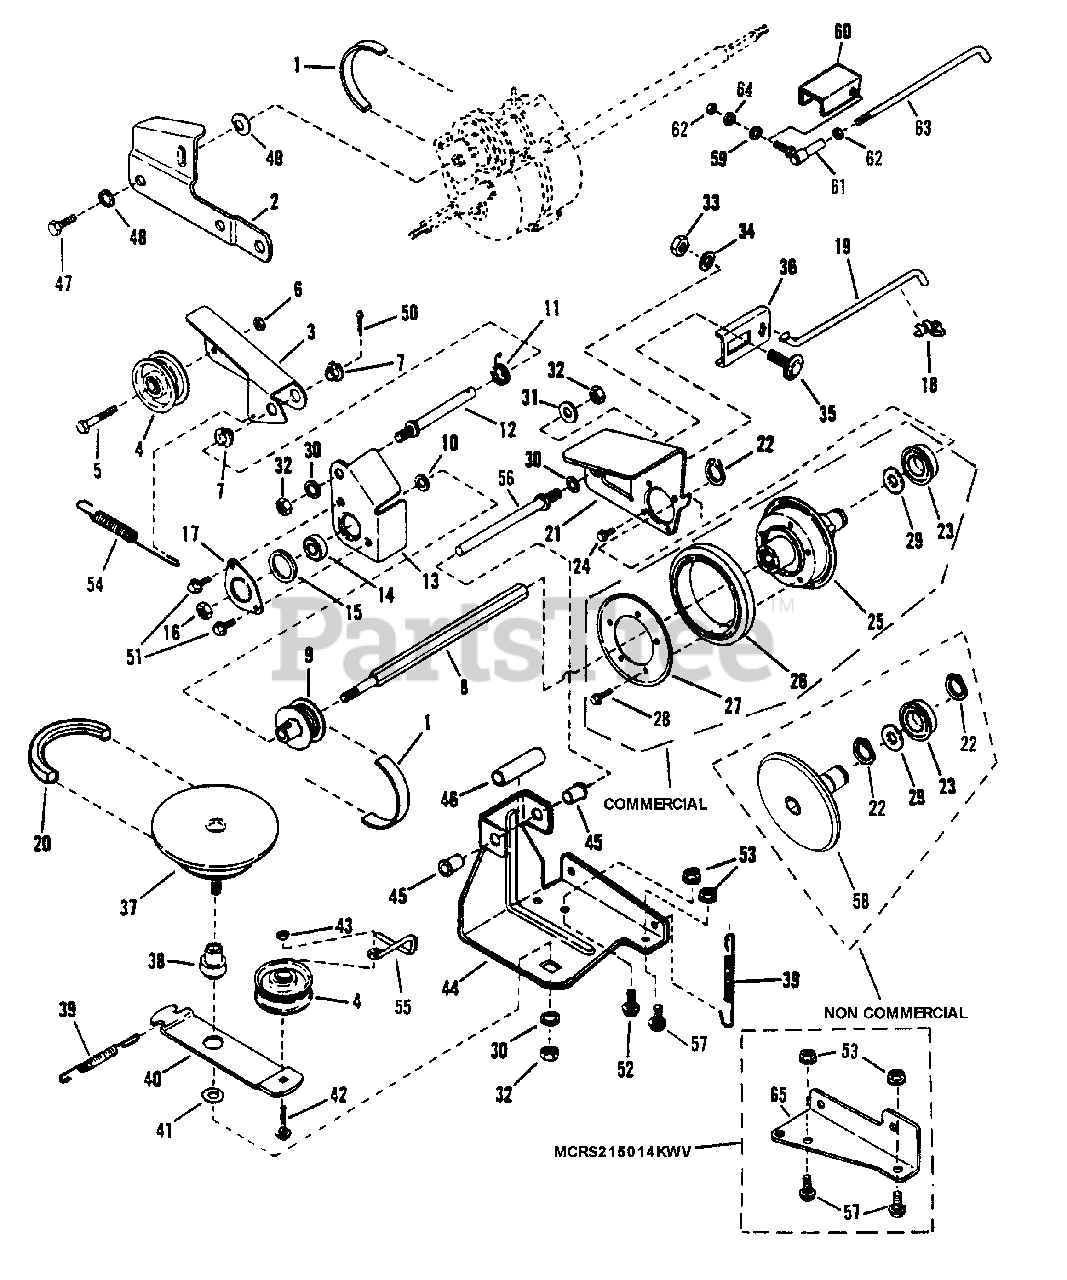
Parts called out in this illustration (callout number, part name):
1	BELT, Poly-Vee
2	LINK, Differential
3	ARM, Clutch Idler
4	PULLEY, Idler
5	SCREW, 1/4-28 x 1-3/8" Hex Head Cap, Grade 5
6	NUT, 1/4-28 Hex Top Lock
7	BUSHING, 3/8 I.D. Nylon
8	SHAFT, Hex Drive
9	PULLEY, Poly-V (2" O.D.)
10	WASHER, 3/8" Flat
11	SPRING, Torsion
12	STUD
13	HOLDER, Bearing (Inner Half)
14	BEARING, Ball
15	O-RING
16	NUT, 3/8-24 Hex Center Lock, Grade 5
17	HOLDER, Bearing (Outer Half)
18	CLIP, 1/4 Right Arc (Transfer Rod)
19	ROD, Transfer
20	BELT, Engine Drive
21	PLATE, Thrust
22	RING, Retaining
23	BEARING, Ball
24	SCREW, #10-32x1/4" Self-Tapping Machine
25	ASSEMBLY, Hub (Includes 7011108 Bushing & 7090913 Screws)
26	RING, Driven
27	PLATE, Ring Retaining
28	SCREW, #10-24 x 1/2" Self-Tapping Machine (Torx)
29	WASHER, 3/4 Shim
30	WASHER, 3/8 Internal Tooth Lock
31	WASHER, 3/8" Flat
32	NUT, 3/8-24 Hex, Grade B
33	NUT, 5/16-18 Hex, Grade 5
34	WASHER, 5/16 Split Lock
35	BOLT, 5/16-18 x 3/4" Carriage, Grade 5
36	CONNECTOR, Transfer Rod
37	KIT, Drive Disc Assembly
38	BUSHING
39	SPRING (Wheel Drive & Idler)
40	ARM, Idler
41	RETAINER, 3/8" Bolt
42	BOLT, 1/4-20 x 1-1/2" Carriage, Grade 5
43	NUT, 1/4-20 Hex Center Lock, Grade 5 or B
44	ASSEMBLY, Deck Bracket
44	BRACKET, Deck
45	BUSHING, Flange Plastic
45	BUSHING, Flange
46	SPACER
47	SCREW, 5/16-18 x 1/2" Hex Head Cap, Grade 5
48	WASHER, 5/16 Internal Tooth Lock
49	WASHER, Spring
50	PIN, 3/32 x 1/2" Cotter
51	SCREW, 1/4-20 x 1/2" Self-Tapping
52	BOLT, 5/16-18 x 1/2" Short Neck Carriage, Grade 5
53	NUT, 5/16-18 Hex Flange Lock, Grade 5
54	SPRING, Clutch
55	SCRAPER, Drive Pulley
56	GUIDE, Thrust Plate
57	BOLT, 5/16-18 x 5/8" Short Neck Carriage, Grade 5
58	DISC, Driven (Cantilever)
59	WASHER, 1/4" Internal Tooth Lock
60	SHIELD, Hex Shaft
61	JOINT, Ball
62	NUT, 1/4-28 Hex Grade 5
63	LINK, Transfer
64	WASHER, 1/4" Flat
65	BRACKET, Strap
